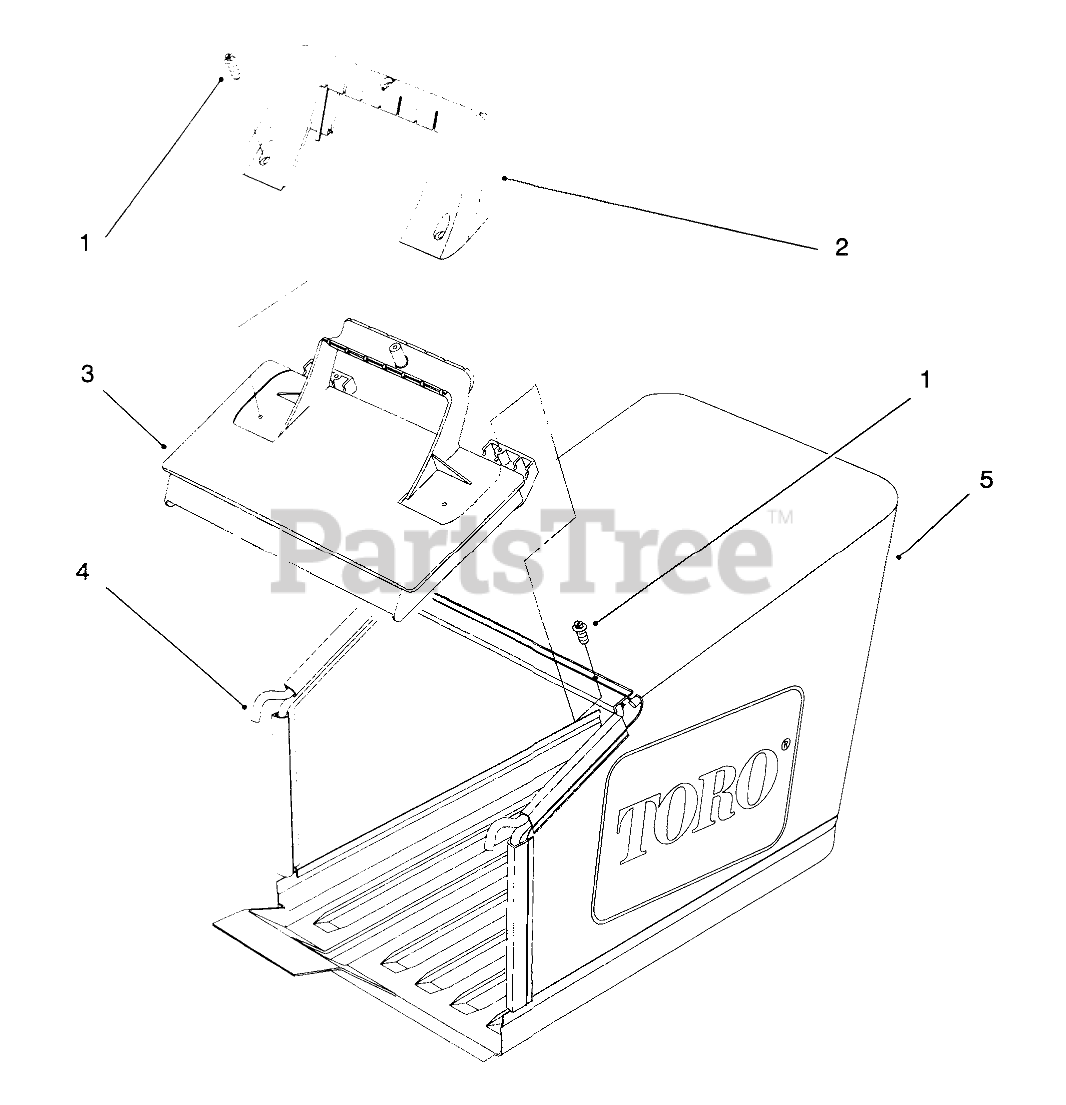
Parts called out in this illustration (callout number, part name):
1	SCREW-PPH
2	HANDLE-DOOR
3	DOOR-BAG
4	Frame
5	GRASS BAG 48CM W/PAN
